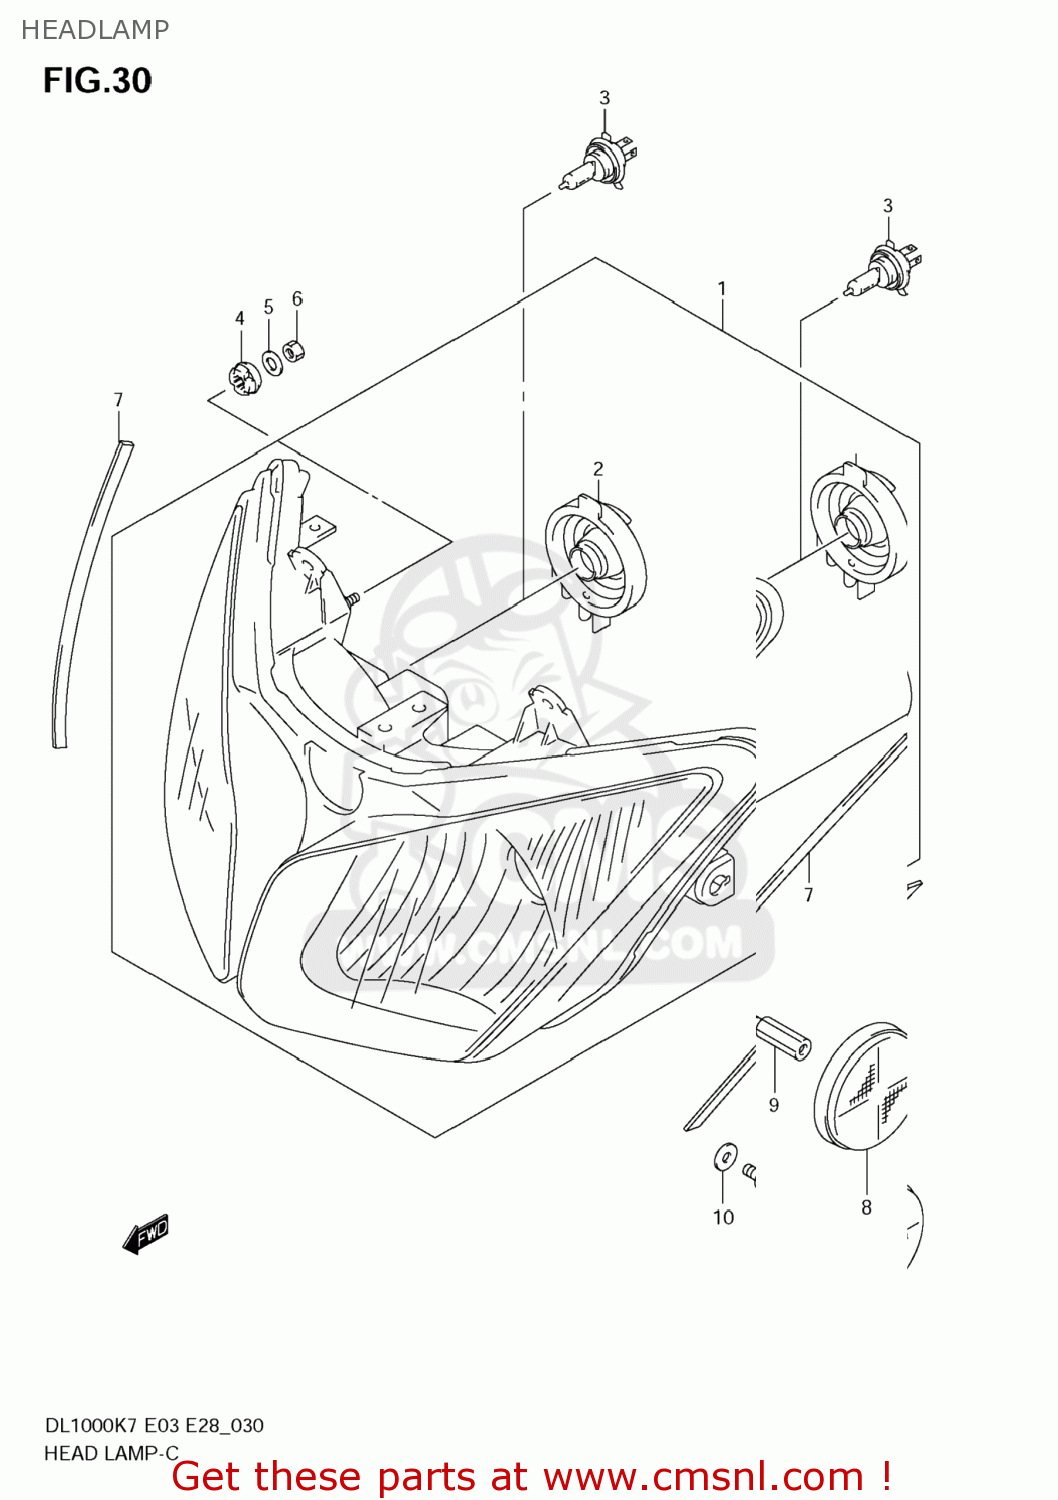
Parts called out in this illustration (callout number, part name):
1	HEADLAMP ASSY
2	COVER,SOCKET
3	BULB(12V60/55W,H4)
4	CUSHION
5	WASHER(6.5X20X1.6)
6	NUT
7	CUSHION,HEADLAMP
8	REFLECTOR,REFLEX
9	BOLT(5X10)
10	WASHER
